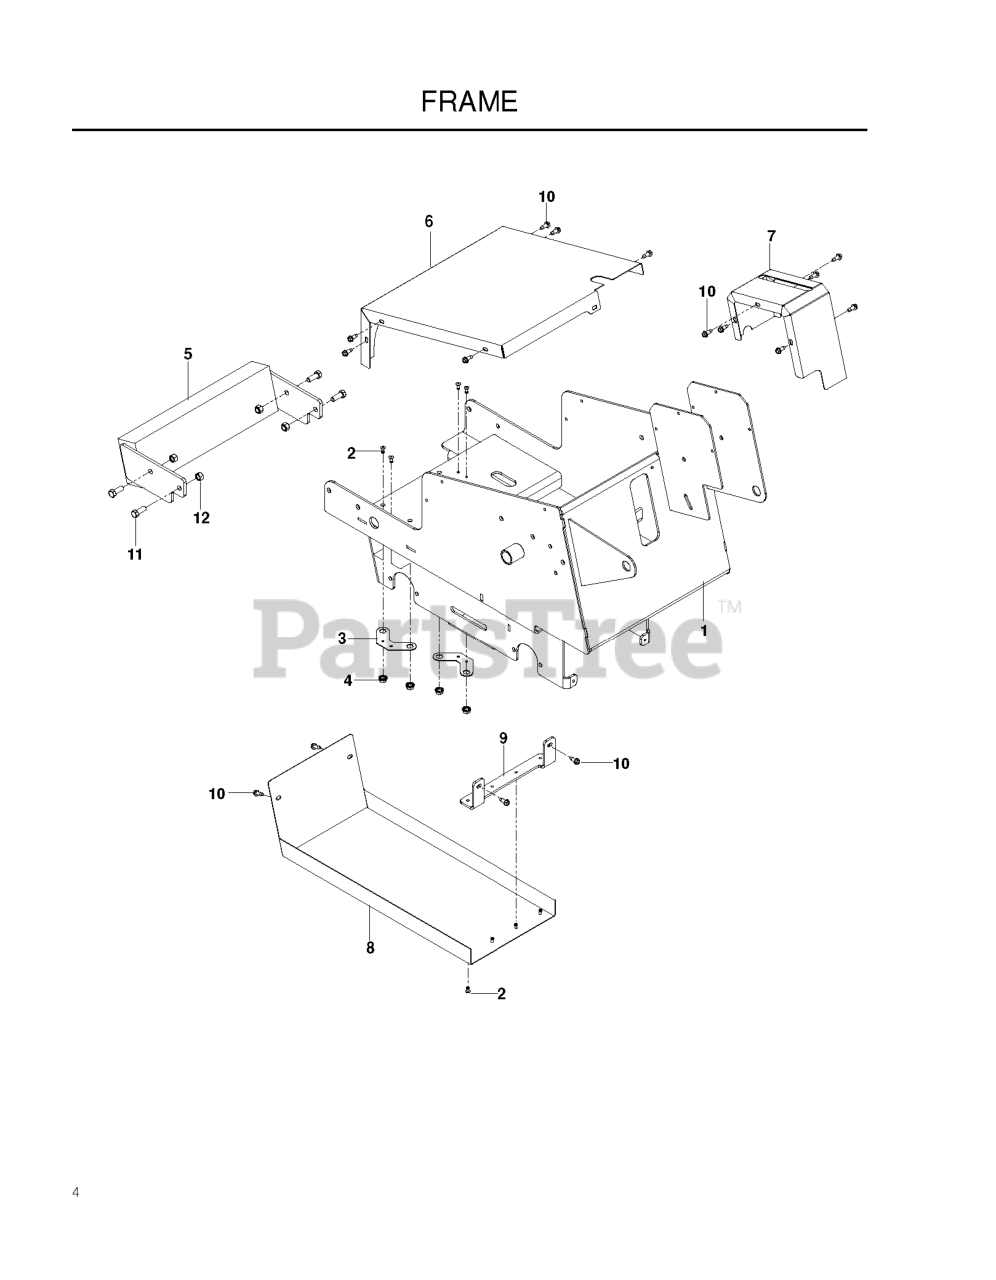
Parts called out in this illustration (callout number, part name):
1	CHASSIS - ORANGE
2	RIVERT, 3/16, STAVEX
3	NUT PLATE, BLACK
4	5/16-18 NYLOC FLANGE NUT
5	WLDMT - WEIGHT, BLACK
6	COVER - TOP, ORANGE
7	COVER - SHIFT, ORANGE
8	BELLY PAN, ORANGE
9	NUT 3/8-16 NYLOC
9	END BRACKET, ORANGE
10	SCREW 1/4 X 5/8
11	HCS 3/8-16X1.GRD.5.ZD
12	NUT 3/8-16 NYLOC
